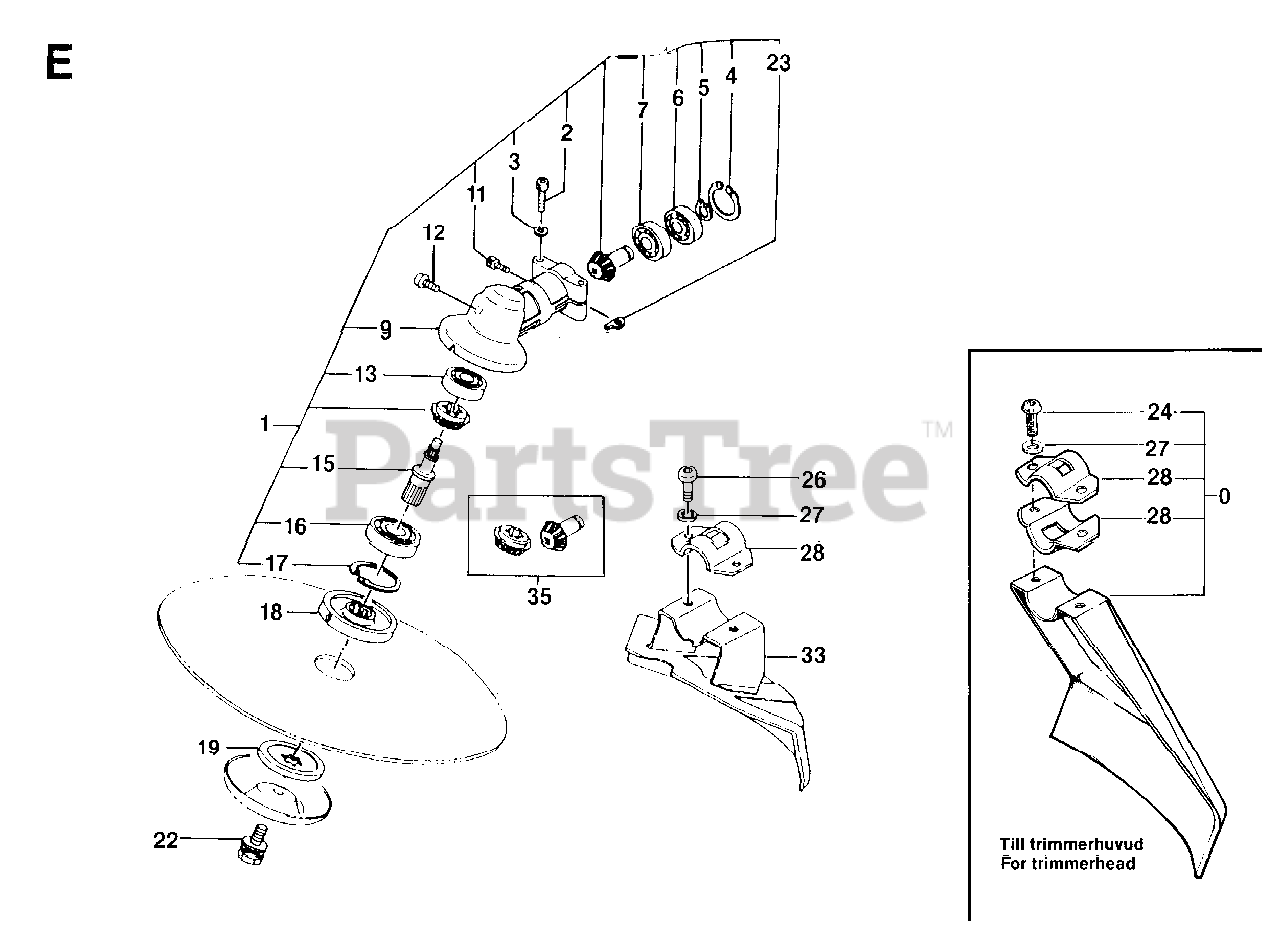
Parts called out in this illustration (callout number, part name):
2	SCREW MC6S 5X25
3	SPRING WASHER
4	RETAINING RING
5	RETAINING RING
11	SCREW MC6S 5X10
24	SCREW MC6S 6X16
27	SPRING WASHER
